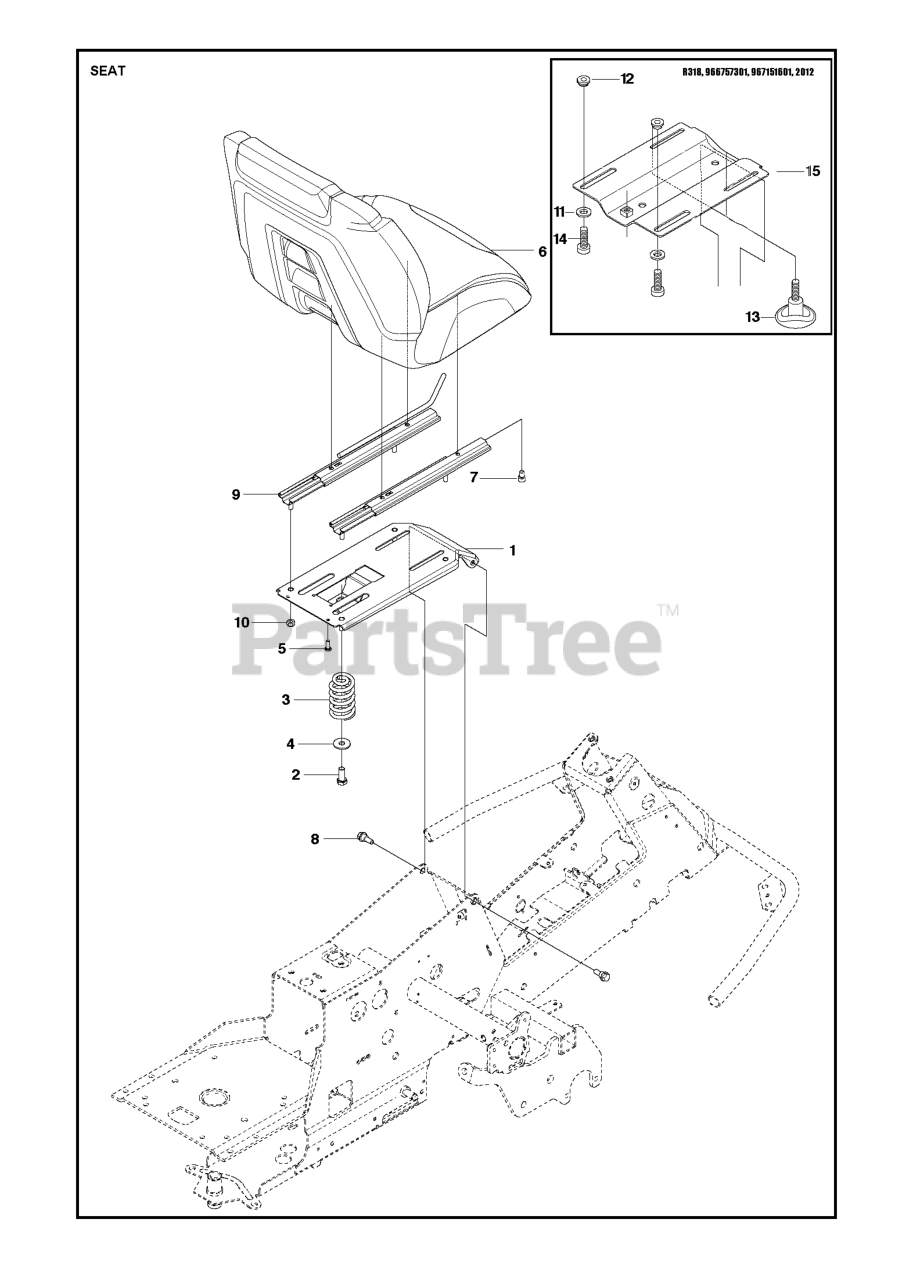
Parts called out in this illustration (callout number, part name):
1	SEAT BRACKET 300 ASSY GREY
2	Screw M10x25
3	SEAT SPRING
5	SCREW
6	SEAT HUSQVARNA HIGH BACK
6	SEAT ASSY KIT HIGH HVA
7	SCREW IHSCM
9	SEAT ADJUSTER LEFT & RIGHT
10	LOCKNUT M8
11	SPACER
12	WASHER
13	ADJUSTING KNOB
14	BOLT
15	SEAT BRACKET
